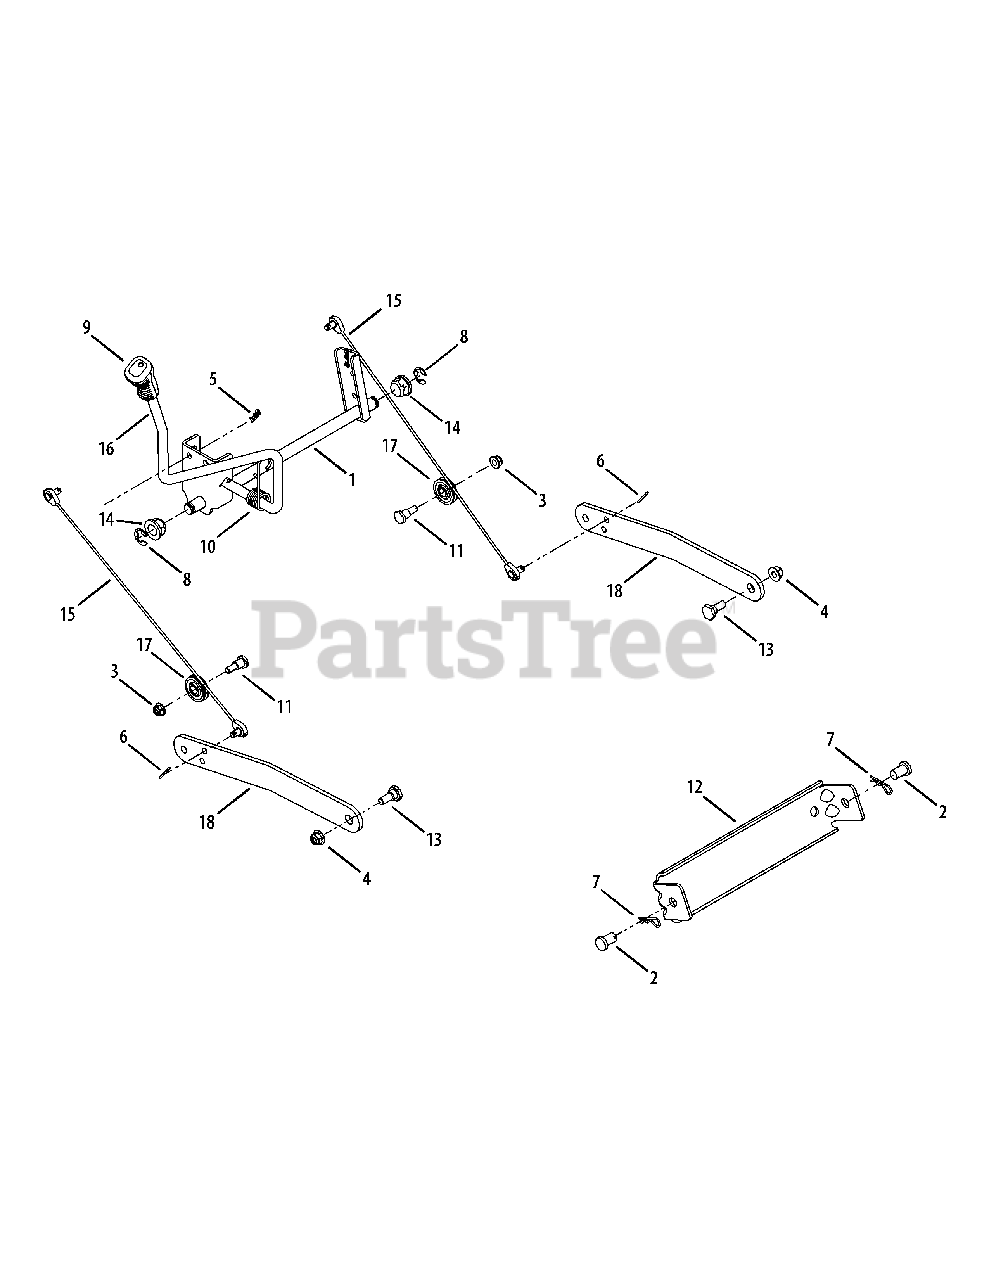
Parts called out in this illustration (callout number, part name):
1	Shaft Assembly, Lift (54" Deck)
2	Pin, Clevis, .50 Dia x .78 Lg
3	Nut, Nylon Lock, 5/16-18, Gr5
4	Nut, Nylon Lock, 3/8-16
5	Pin, Cotter, .072 Dia. x 1.13 Lg
6	Pin, Cotter, 3/32, 1.0
7	Pin, Click, .092 x 1.64 Lg
8	E-ring, .625 Dia. Shaft
9	Grip, Handle
10	Spring, Torsion
11	Screw, Hex Cap, 5/16-18x.620 Gr2
12	Bracket, Deck
13	Shldr. Screw, 3/8-16
14	Bearing, Hex Flange
15	Cable, Lift, 16.16 Lg
16	Handle, Lift
17	Pulley, Roller
18	Arm, Lift
